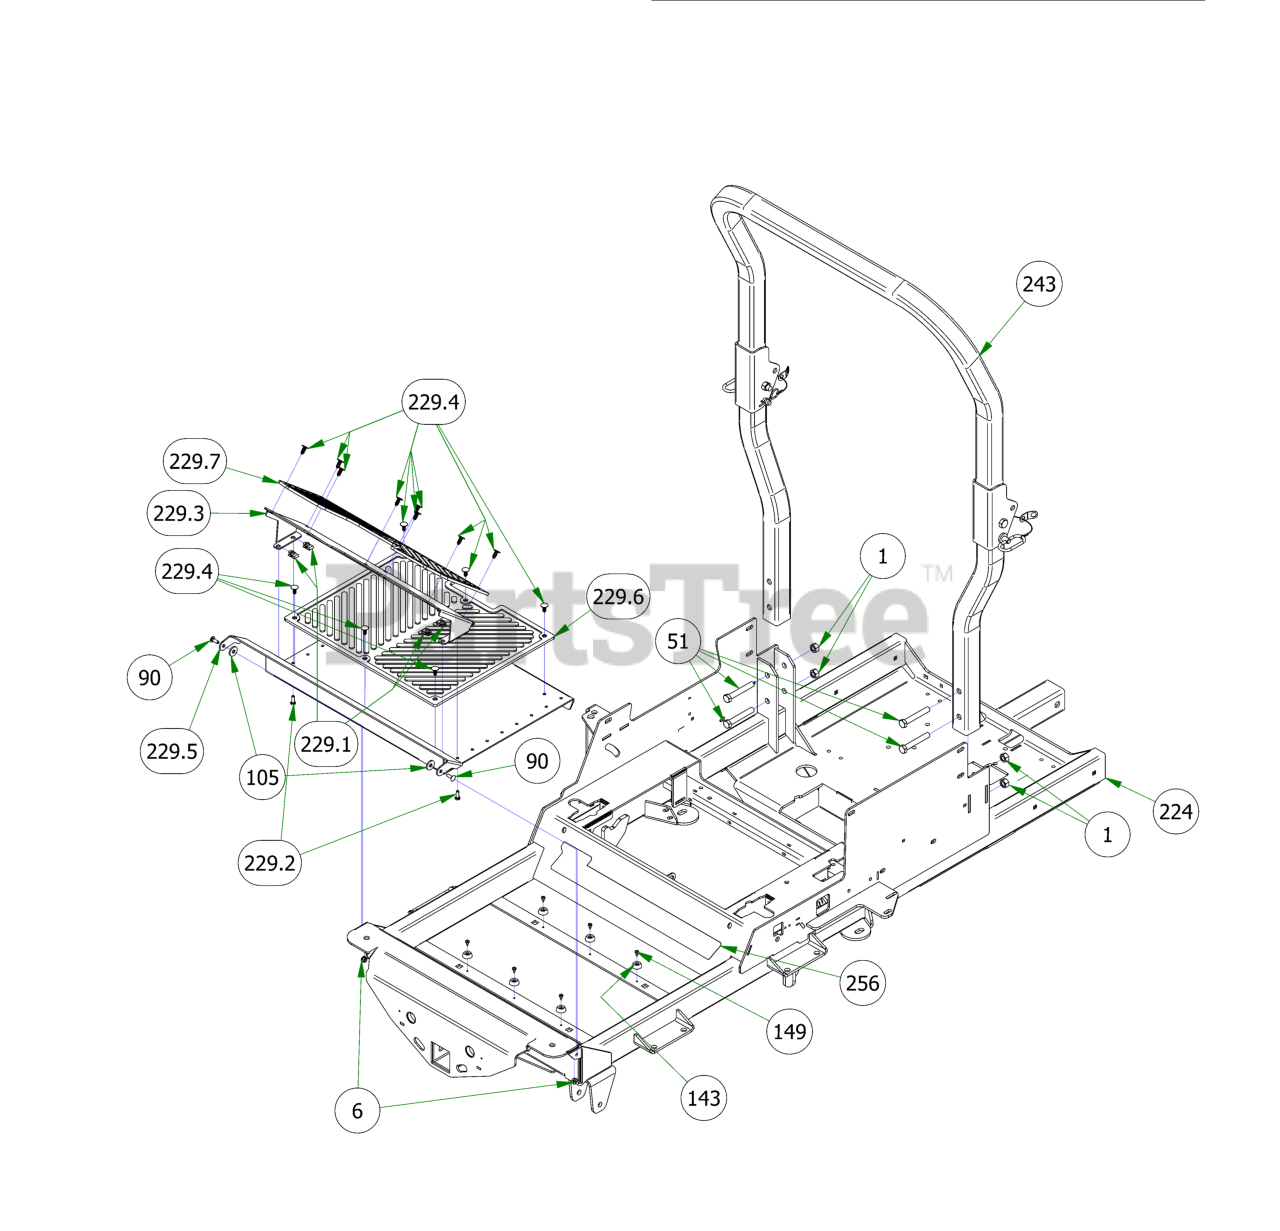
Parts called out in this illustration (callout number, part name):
1	1/2-13 HEX 2-WAY REVERSIBLE CENTER LOCKNUT Grade B ZINC
6	1/4-20 NYL INSERT FLANGE LOCKNUT ZINC
51	1/2-13 X 3-1/4 HEX CAP SCREW (GR.5) ZINC
90	1/4-20 X 3/4 CARRIAGE BOLT ZINC
105	.360 ID X .983 OD X .120 THICK FLAT WASHER NYLON
143	Button Bumper
149	10-16 X 1/2 PAN PHIL TEK/3 CLIMASEAL OR ACF-SILVER COATED
224	2019 Renegade Gas Frame - Powdercoated
229	R-Series Floorboard Assembly
229.1	1/4-20 Cage Nut
229.2	1/4-20 X 3/4 HEX CAP SCREW (GR.5) ZINC
229.3	OUTLAW ADJUSTABLE FOOT PLATE-ORANGE
229.4	Ratchet Fastener
229.5	2019 Outlaw Floorboard
229.6	MAT (FLOOR)
229.7	MAT (FOOT PLATE)
243	2019 2X2 Folding ROPS
256	2019 Renegade Cooler Cover Decal
267	Independetly Articulating Front Suspension Arms Patent Decal
